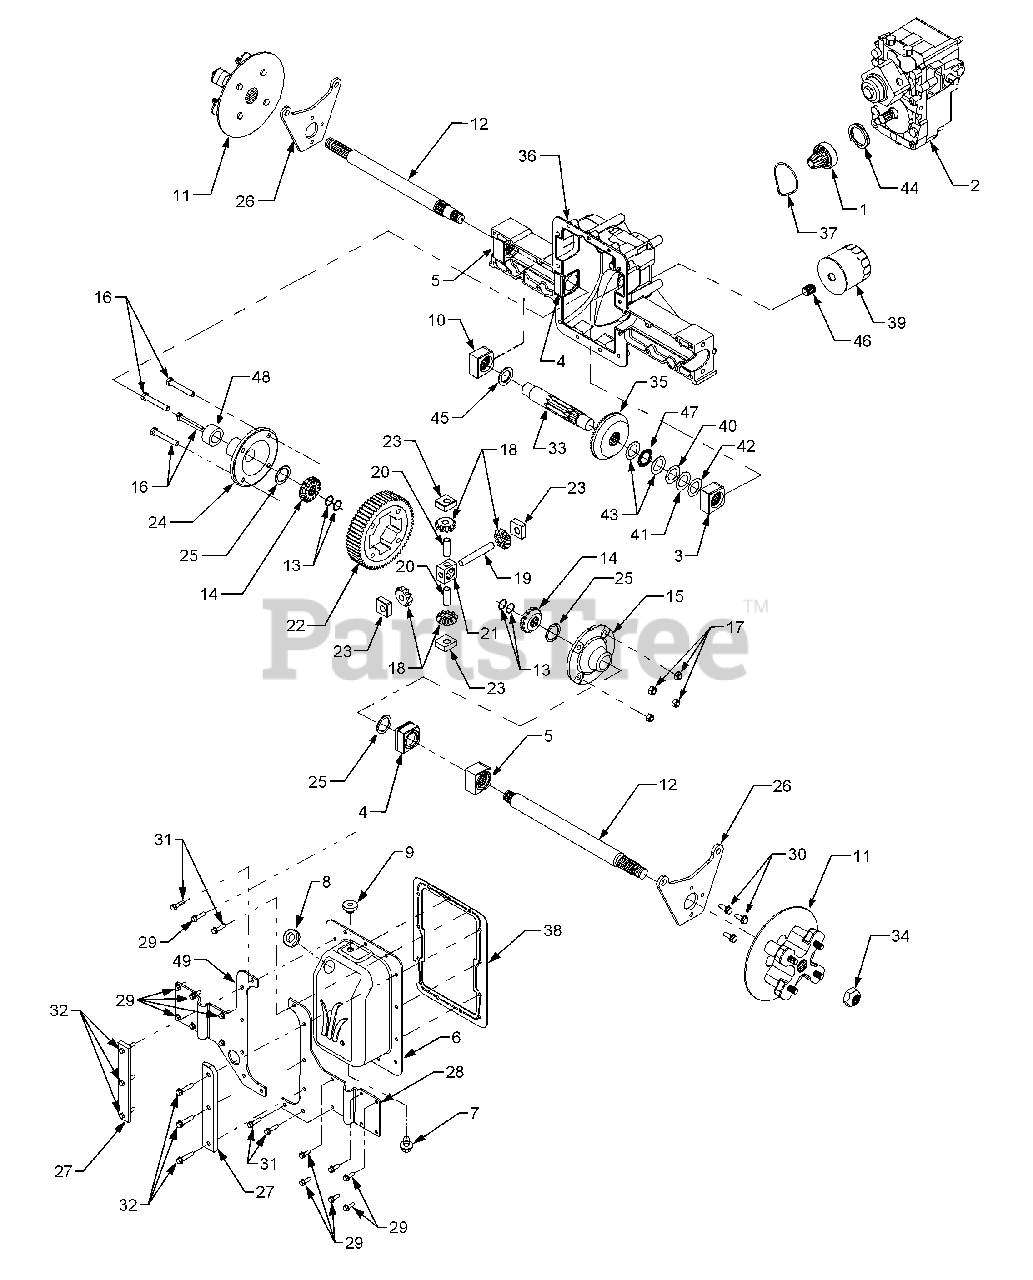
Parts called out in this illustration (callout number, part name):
1	Gear Assembly, Pinion 13T
2	Hydrostatic Transmission Assy. Kit
3	Bearing Block Assembly, Needle
4	Bearing Block Assembly
5	Bearing Block Assembly
6	Cover Assembly, Rear
7	Plug, Drain, M14 x 1.5 x .827
8	Grommet, Rubber
10	Bearing Block Assembly
11	Hub Assembly, Wheel
12	Axle Shaft, 15.08 Long
13	Retaining Ring
14	Gear, Spur, 14T
15	Housing, Diff. Cover
16	Hex Cap Screw, 3/8-24 x 2.25 GR5
17	Nut, Hex Lock, 3/8-24
18	Gear, Differential 10T
19	Shaft, Cross, .5 x 3.485
20	Shaft, Cross, Special
21	Differential Pinion Block
22	Gear, Spur 60T
23	Block, Thrust Miter
24	Housing, Differential Cover
25	Washer, Flat, 1.187 x 1.56 x .062
26	Bracket, Brake Mounting
27	Block, Transmission Cover
28	Plate, Trans. Support RH
29	Screw, Hex Wash. Hd. Tapp 1/4-20 x .75
30	Screw, Hex Wash. Hd. Tapp 5/16-18 x .875
31	Screw, Hex Wash. Hd. Tapp 1/4-20 x 1.0
32	Screw, Hex Wash. Hd. Tapp 1/4-20 x 1.25
33	Shaft, Output 9T
34	Nut, Lock, 7/8-14
35	Gear, Bevel 54T
36	Housing Kit, Differential
37	O-Ring, 2.75 x .103
38	Gasket
39	Filter, Oil
40	Washer, Flat Shim, 1.0 x 1.56 x .010
41	Washer, Flat Shim, 1.0 x 1.56 x .020
42	Washer, Flat Shim, 1.0 x 1.56 x .015
43	Washer, Thrust, 1.007 x 1.542 x .03
44	Washer, Spring
45	Washer, Flat, 1.01 x 1.86 x .060
46	Fitting, Filter Nipple
47	Bearing, Needle Thrust
48	Spacer, Axle, 1.188 x 1.665 x .67
49	Plate, Trans. Support LH
